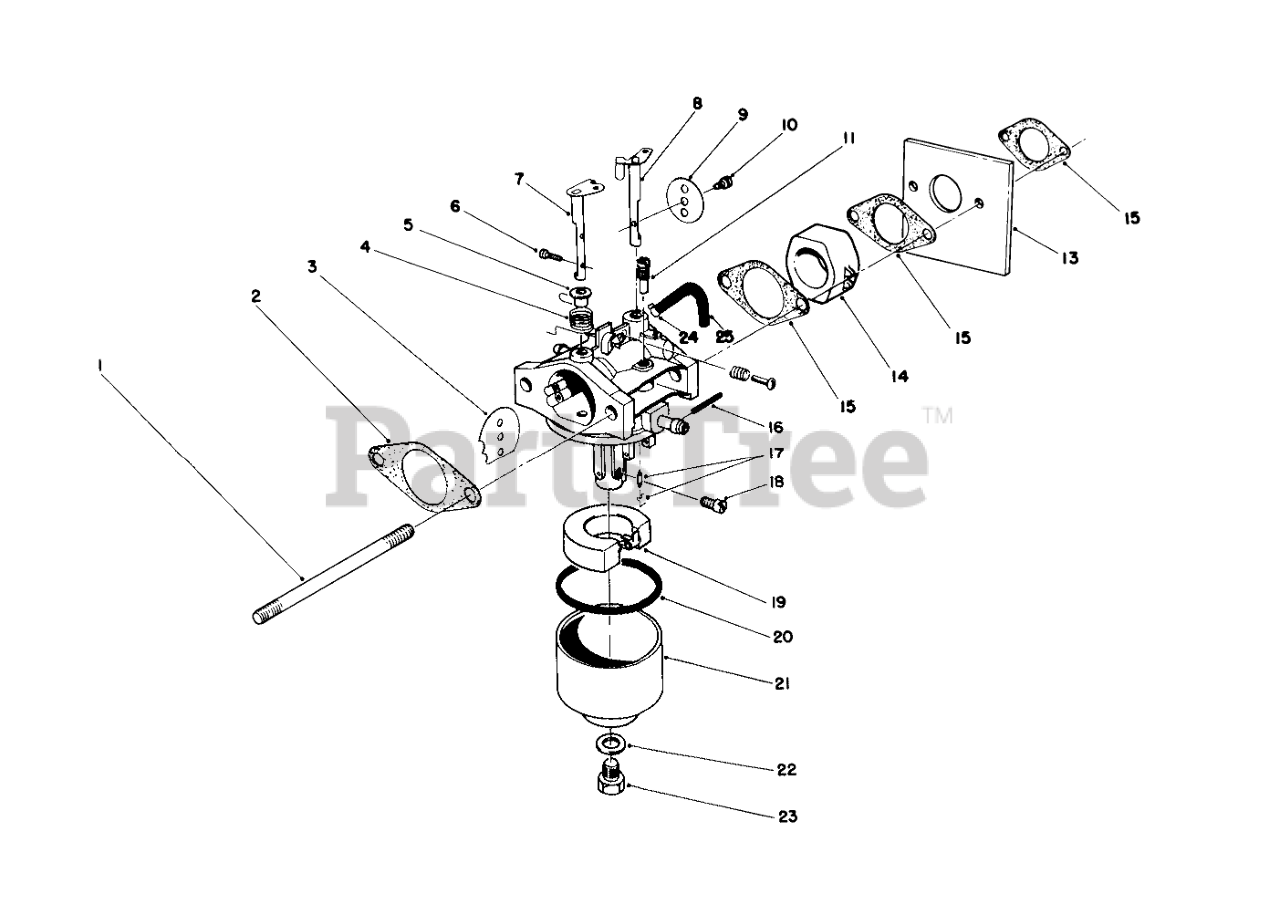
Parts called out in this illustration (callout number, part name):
1	STUD-CARBURETOR
2	GASKET-AIR CLEANER
3	PLATE
4	SPRING
5	BUSHING
6	SCREW
7	SHAFT-CHOKE
8	SHAFT
9	PLATE
10	Screw-Throttle
11	PILOT JET
13	SHIELD-CARBURETOR
14	INSULATOR-CARBURETOR
15	GASKET-CARB
16	Pin
17	NEEDLE
18	JET-MAIN
19	FLOAT
20	GASKET
21	BOWL - FLOAT
22	GASKET
23	SCREW
24	CLAMP
25	VENT TUBE
